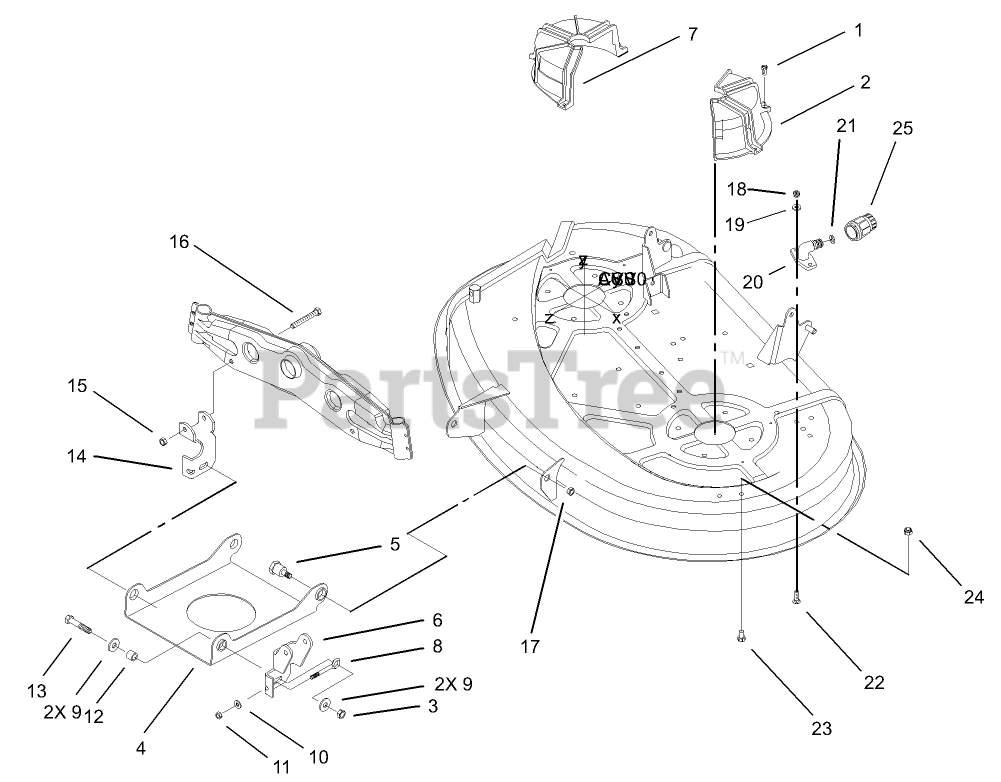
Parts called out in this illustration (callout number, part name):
1	SCREW-HWHTF
2	GUIDE-BELT, LH
3	NUT-LOCK, NI
4	PAN-DECK SUSPENSION, FRONT
6	BRACKET-SUSPENSION, LH
7	GUIDE-BELT, RH
8	SCREW-ADJUSTING
9	WASHER-HARDENED
10	WASHER-FLAT
11	NUT-LOCK, NI
12	SPACER
13	SCREW-HH
14	BRACKET-SUSPENSION, RH
15	NUT-LOCK, NI
16	SCREW-HH
17	NUT-LOCK, NI
18	NUT-LOCK, NI
19	WASHER-FLAT
21	O-RING
22	BOLT-CARR
23	SCREW-HH
24	NUT-LOCK, NI
25	CONNECTOR-HOSE
